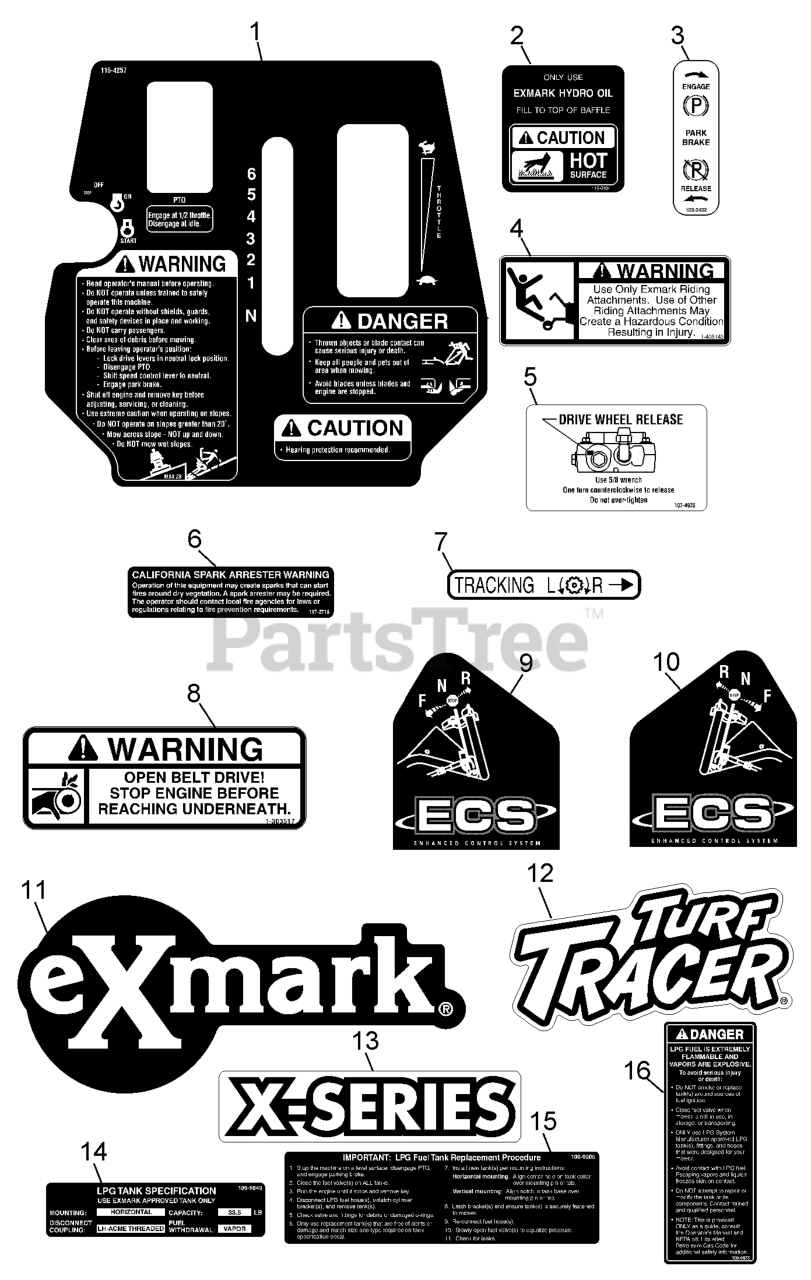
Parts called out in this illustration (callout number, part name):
1	DECAL,CONSOLE TTX
2	DECAL-HYDRAULIC TANK
3	DECAL,PARKING BRAKE
4	DECAL,SULKY WARNING
5	DECAL,DRIVE RELEASE
6	DECAL-ARRESTER, SPARK
7	DECAL,TRACKING ADJUST
8	DECAL,BELT DRIVE
9	DECAL,LH ECS INSTRUCTION
10	DECAL,RH ECS INSTRUCTION
11	DECAL,EXMARK LOGO
12	DECAL,TTH MODEL
13	DECAL-X-SERIES
14	DECAL,LPG TANK SPEC HORIZ
15	DECAL-TANK REPLACEMENT
16	DECAL-LPG WARNING
